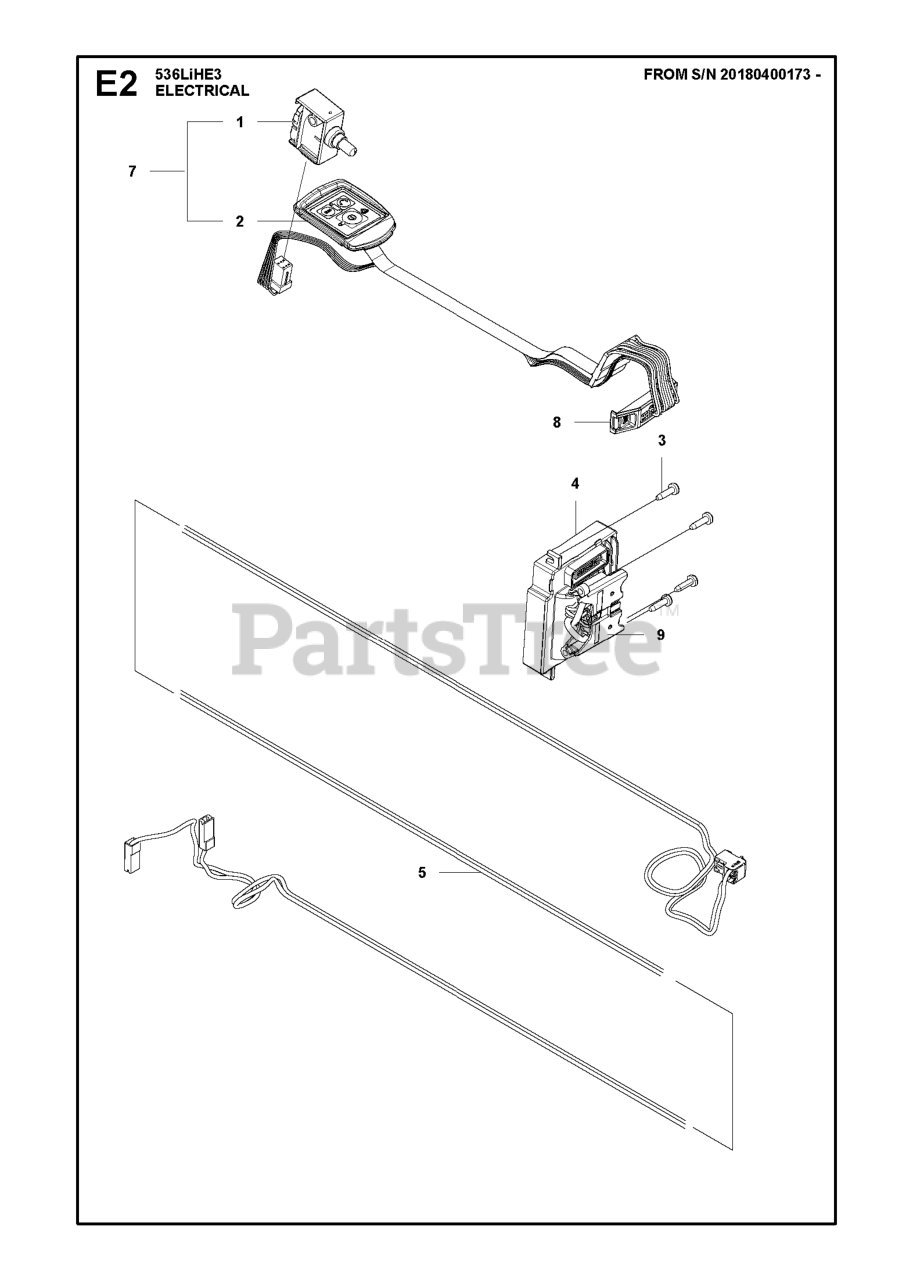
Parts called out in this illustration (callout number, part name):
1	TRIGGER SWITCH IPX4
2	WIRING ASSY POLE HEDGE MAIN
3	SCREW CITXPANT
4	CONTROL UNIT BLDC - 536LIHE3
5	WIRING ASSY POLE HEDGE MOTOR B
7	SWITCH KIT BATTERY POLE HEDGER
9	CONNECTOR BATTERY
